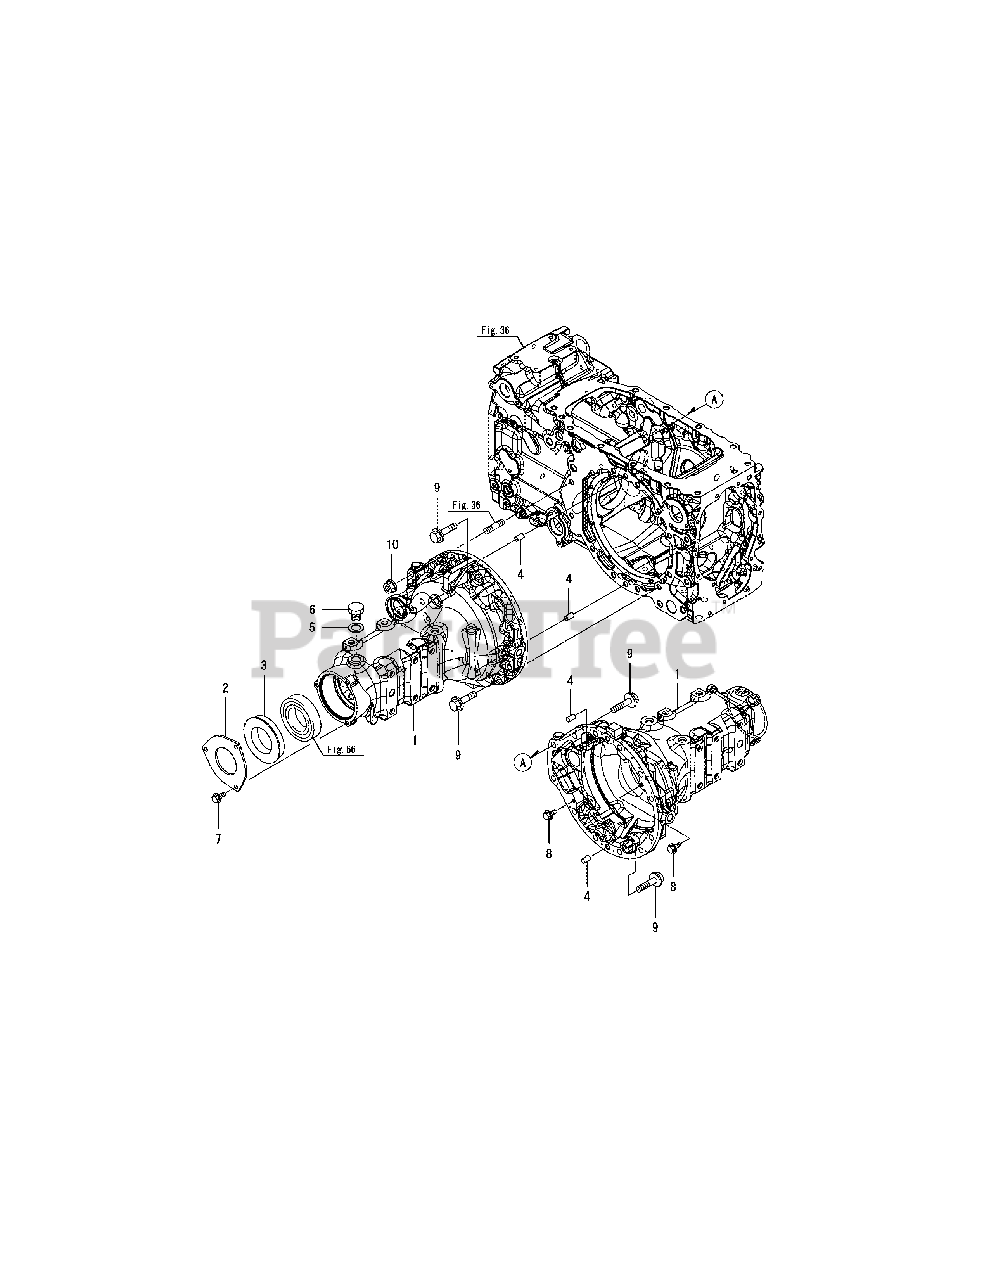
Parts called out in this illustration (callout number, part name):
1	HOUSING, REAR AXLE
3	SEAL, AXLE SHAFT
4	PARALLEL PIN 10X 18
7	BOLT M 8X 16 PLATED
8	BOLT M 8X 16 PLATED
